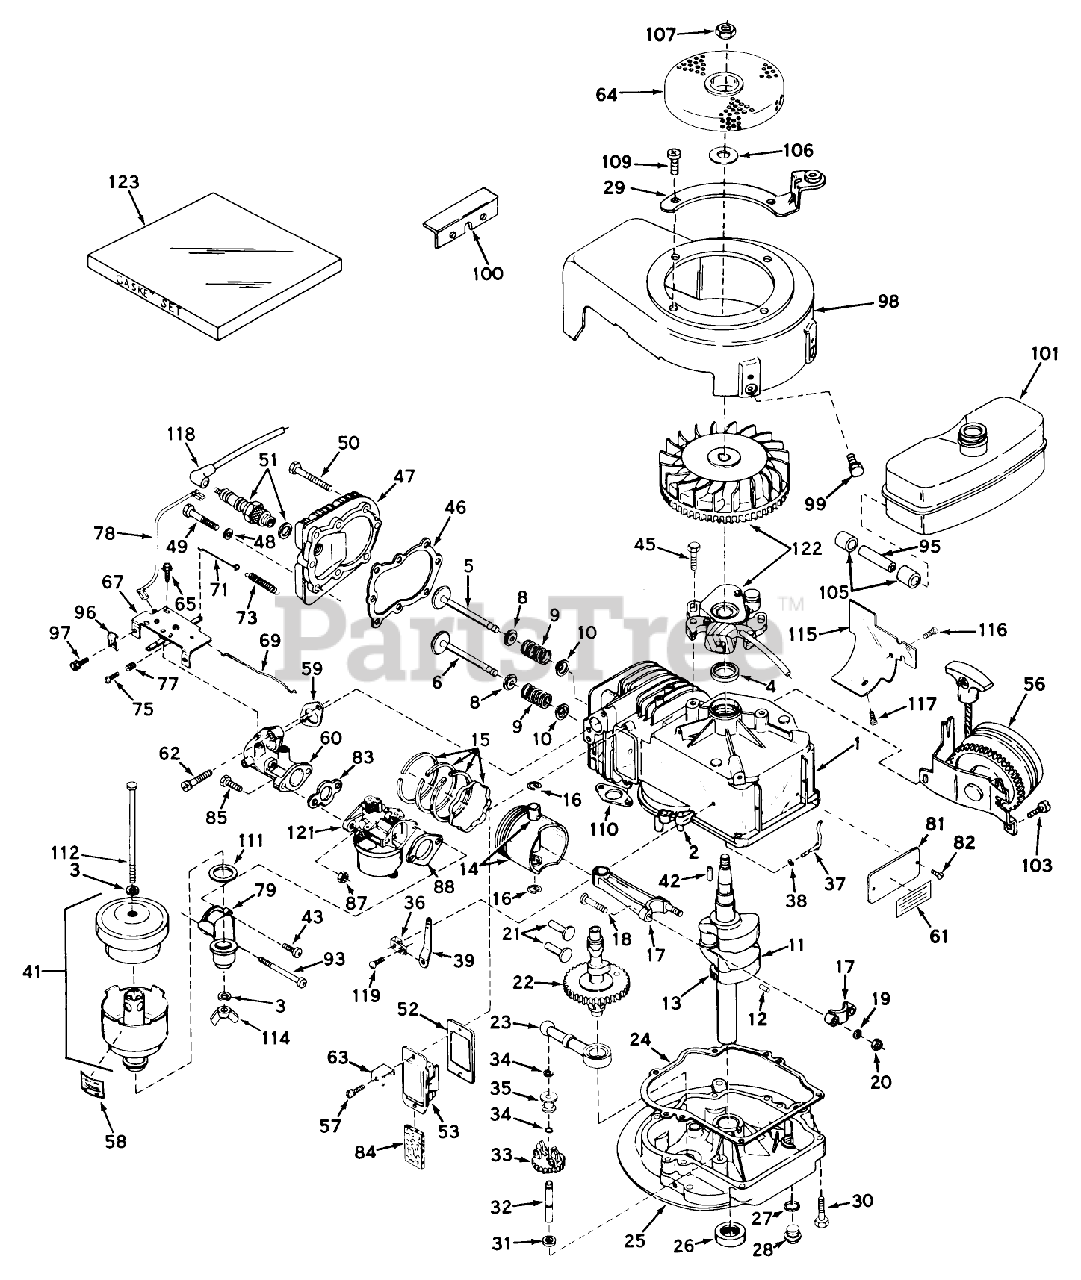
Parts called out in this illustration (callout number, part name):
1	Cylinder Assy. (Incl. Ref. 2 4)
2	Pin-Dowel
3	Washer Fibre
4	OIL SEAL
5	Valve, Intake (Incl. Ref. #38, 39 40) (Std.)
5	Valve, Intake(1/32"overs.)(Incl. Ref. 8, 9 10)
6	Valve, Exhaust (Standard)(Incl. Ref. 8, 9 10)
6	Valve, Exhaust (1/32" Overs.(Incl. Ref. 8, 9 10)
8	Cap-Upper Valve Spring
9	Spring-Valve
10	Cap-Valve, Spring
11	Crankshaft Assy. (Incl. Ref. 12 13)
12	Pin, Groove
13	Gear, Crankshaft
14	Piston Pin Assy. (Incl. 2 of No. 16)(Standard)
14	Piston Pin Assy. (Incl. 2 of No. 16)(.010 oversize)
14	53020 ADN. TO 28594
15	Piston Ring Set Std.
15	Piston Ring Set .010 O.S.
15	Piston Ring Set .020 O.S.
16	Ring-Retaining, Piston Pin
17	Rod Assy., Connecting (Incl. Ref. #17)
18	Bolt, Connecting
19	Washer
20	LOCKNUT
21	Lifter-Valve
22	Camshaft
23	Oil Pump ASM
24	Gasket, Mounting
25	Flange Assy., Mounting (Incl. Ref. 26, 27, 28 32)
26	Seal Oil
27	Gasket-Oil Drain
28	Plug Oil Drain
29	Bracket Assy., Starter
30	Screw (1/4-20 x 1-1/4)
31	Washer-Flat
32	Shaft-Governor
33	Governor Gear ASM
34	Ring-Retaining
35	Spool-Governor
36	Clamp-Lever, Governor
37	Rod, Governor (Incl. No. 36)
38	Washer-Flat
39	Lever, Governor
41	Cleaner Assy., Air
42	Key Flywheel
43	KIT - SEAL WIPER
45	Screw
46	Gasket-Cylinder Head
47	CYLINDER HEAD
48	Washer
49	Screw
50	Screw
51	SPARK PLUG
52	Gasket Breather
53	Breather Assembly (Incl. Nos. 52 84)
56	Starter, Side Mount
57	Screw
58	Decal, Air Cleaner
59	Gasket, Intake
60	Pipe, Intake
61	480B GIL SNWTHWR O/
62	Screw, Fil. Hd. Sems
63	Retainer Clip
64	Screen, Flywheel
65	Screw (10-24 x 9/16)
67	Control Assy., Speed
69	Link, Throttle to Governor
71	Link, Governor Spring
73	Spring, Governor
75	Screw
77	Spring-Compression
78	Wire, Ground
79	Elbow, Air cleaner
81	IDENTIFICATION PLATE
82	Stud
83	Gasket
84	Element-Breather
87	Nut and Lock Washer (1/4-28)
88	Gasket
93	Screw
95	Line, Fuel
96	Conduit
97	Screw (10-32 x 3/8)
98	Housing, Blower
99	Screw (1/4-20x19/32)
100	Bracket, Shroud
101	Tank, Fuel
103	Screw, Fil. Hd. Sems
105	Line-Fuel (8.62)
106	Washer
107	Hex Nut
109	Screw
110	Gasket Exhaust
111	Gasket, Spacer
112	Bolt, Air Cleaner
114	Nut, Wing
115	Extension, Housing
116	Screw
117	Screw
118	Cover-Spark Plug
119	Screw
121	Carburetor
122	Magneto
123	Gasket Set
